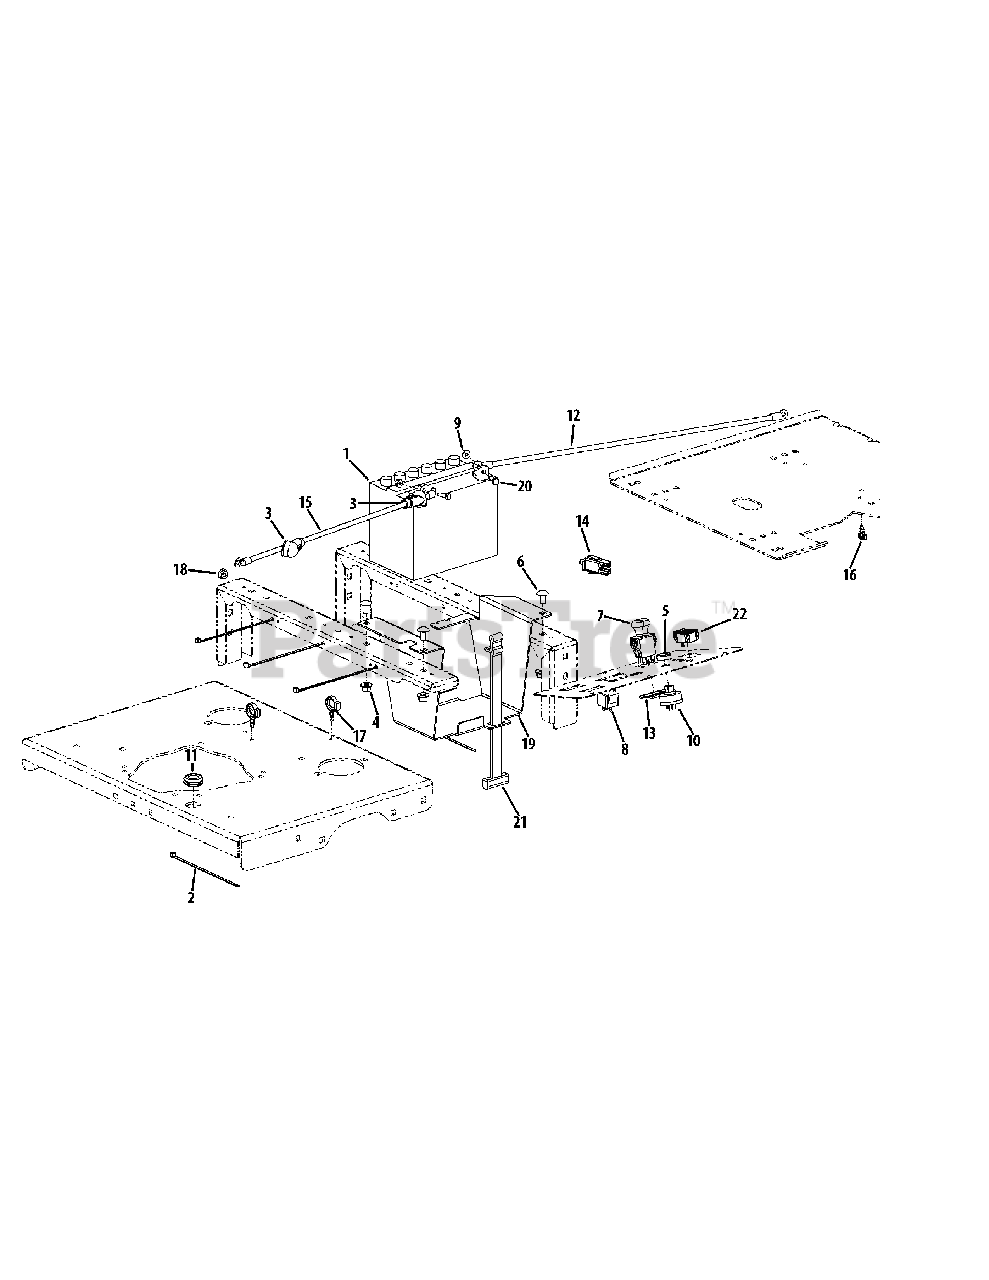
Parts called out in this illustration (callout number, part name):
2	Cable Tie
3	Boot Terminal, 1.00 x 2.50
4	Flange Counter Lock, 3/8-16
5	Ingnition Nut w/ Cap, 5/8-32
6	Carriage Bolt, 3/8-16 x .75
7	PTO Switch
9	Flange Top Lock Nut, 1/4-20
10	Ignition Switch
11	Grommet, .75
12	Batter Cable
13	PTO Switch Bracket
14	Switch
15	Battery Cable
16	Electric CDT Clip, 3/8
17	Electric CDT Clip, 5/8
18	Flange Nut, M8-1.25
21	Battery Strap
22	Hour Meter
